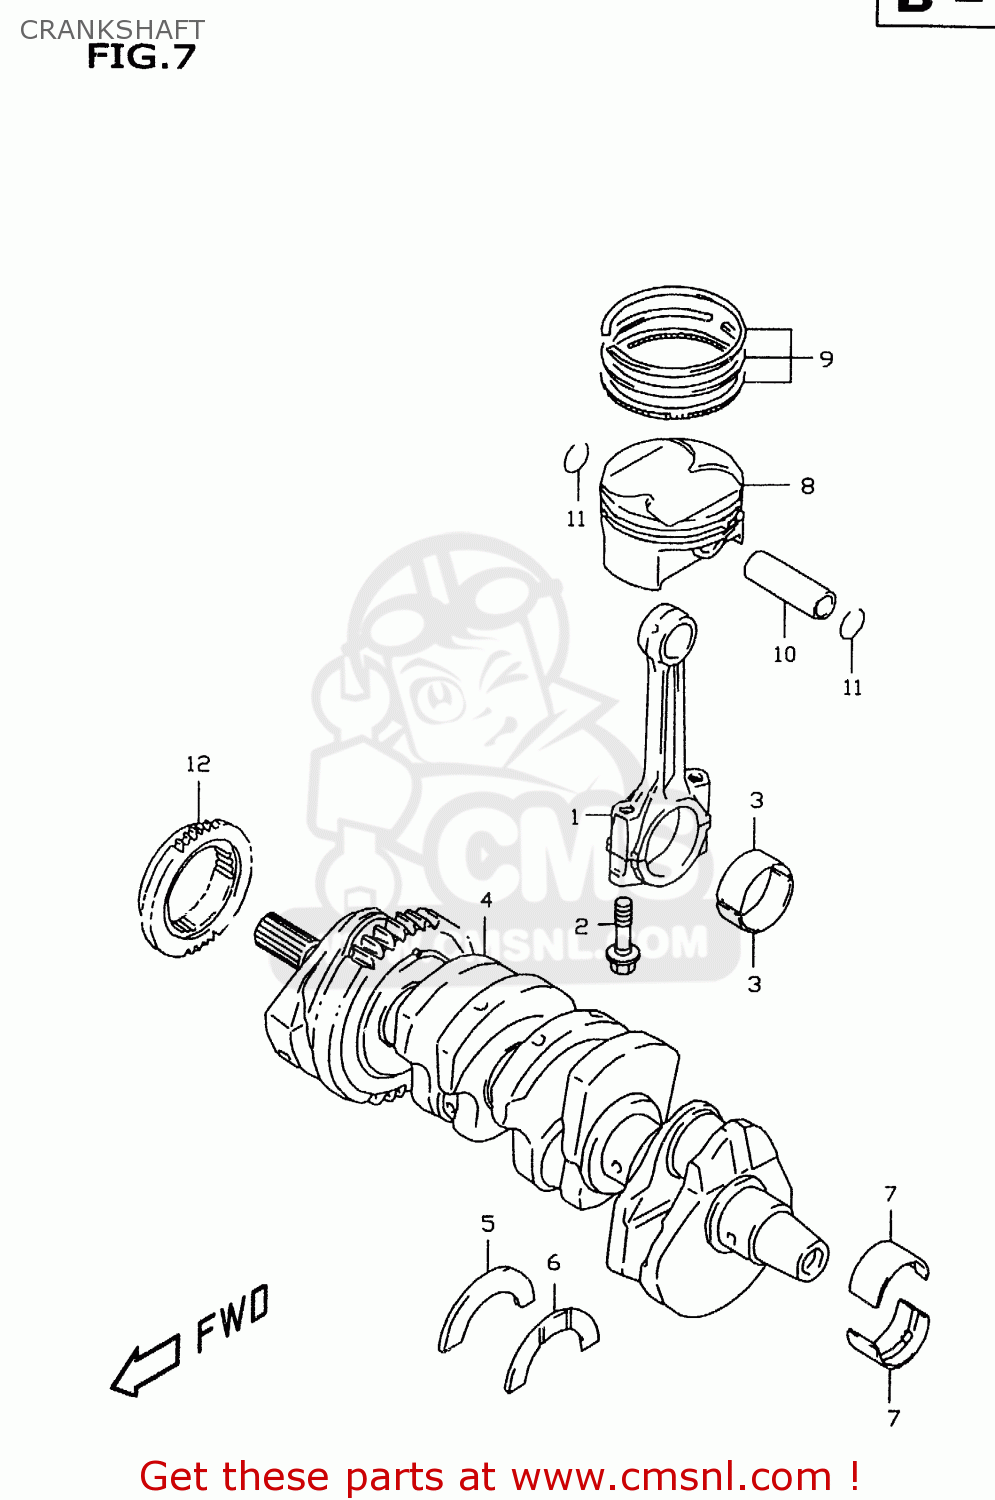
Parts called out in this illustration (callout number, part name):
1	CONNECTING ROD ASSEMBLY
2	BOLT,CONNECTING ROD
3	BEARING,CRANK PIN
4	CRANKSHAFT SET
5	BEARING,CRANK THRUST(GREEN)
6	BEARING,CRANK THRUST(RED)
7	BEARING,CRANKSHAFT
8	PISTON
9	RING SET,PISTON
10	PIN,PISTON
11	CIRCLIP
12	SPROCKET,CAM CHAIN DRIVE
